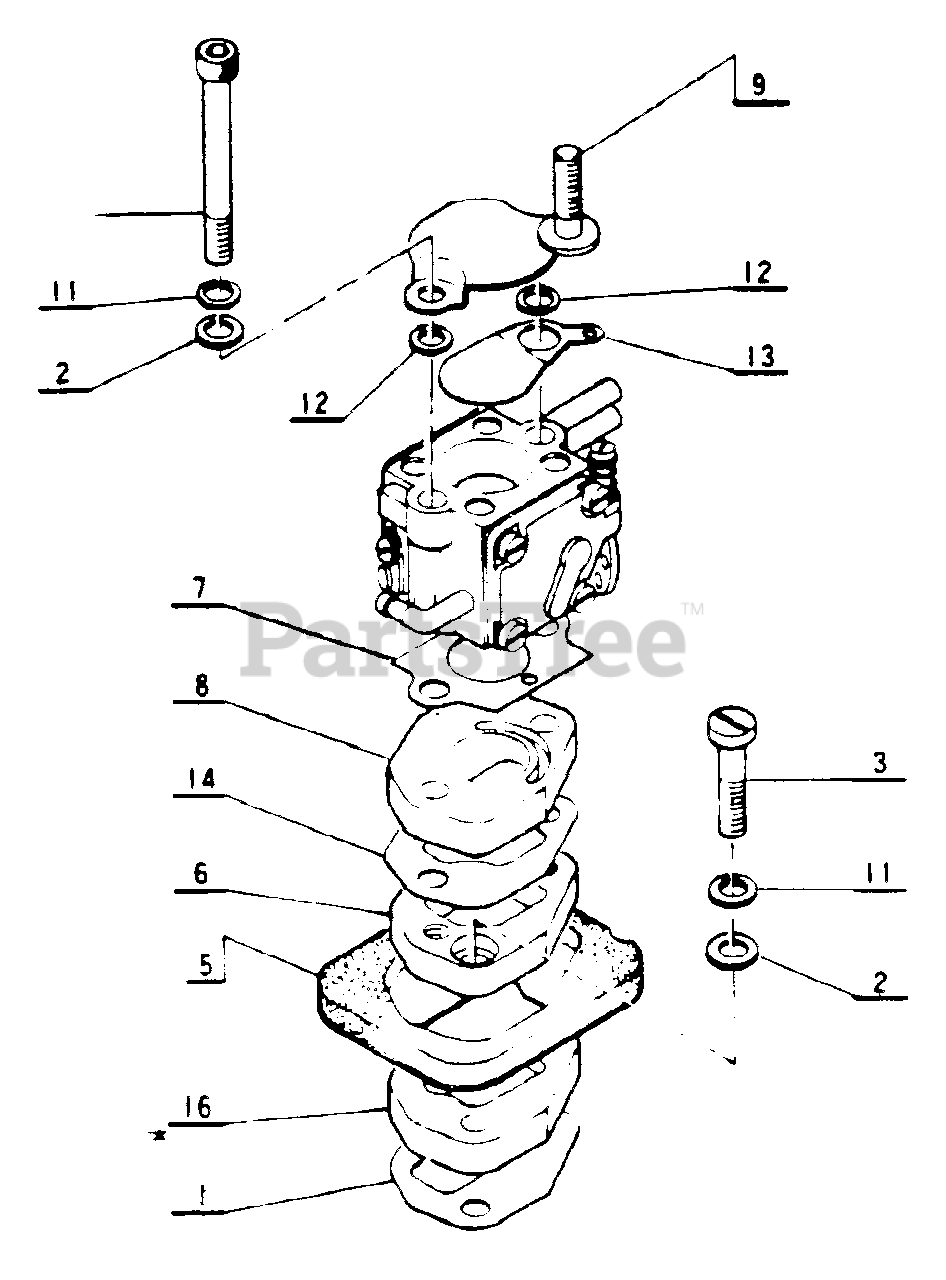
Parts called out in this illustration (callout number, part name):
1	GASKET, INTAKE
2	WASHER - 5
3	BOLT
5	SEAL, DUST
6	CASE, CARBURETOR
7	GASKET, INTAKE
8	INSULATOR
9	PLATE, PREVENT
10	SCREW
11	LOCKWASHER - 5
12	WASHER - 5
13	SHUTTER, CHOKE
14	GASKET, INTAKE
16	INSULATOR
